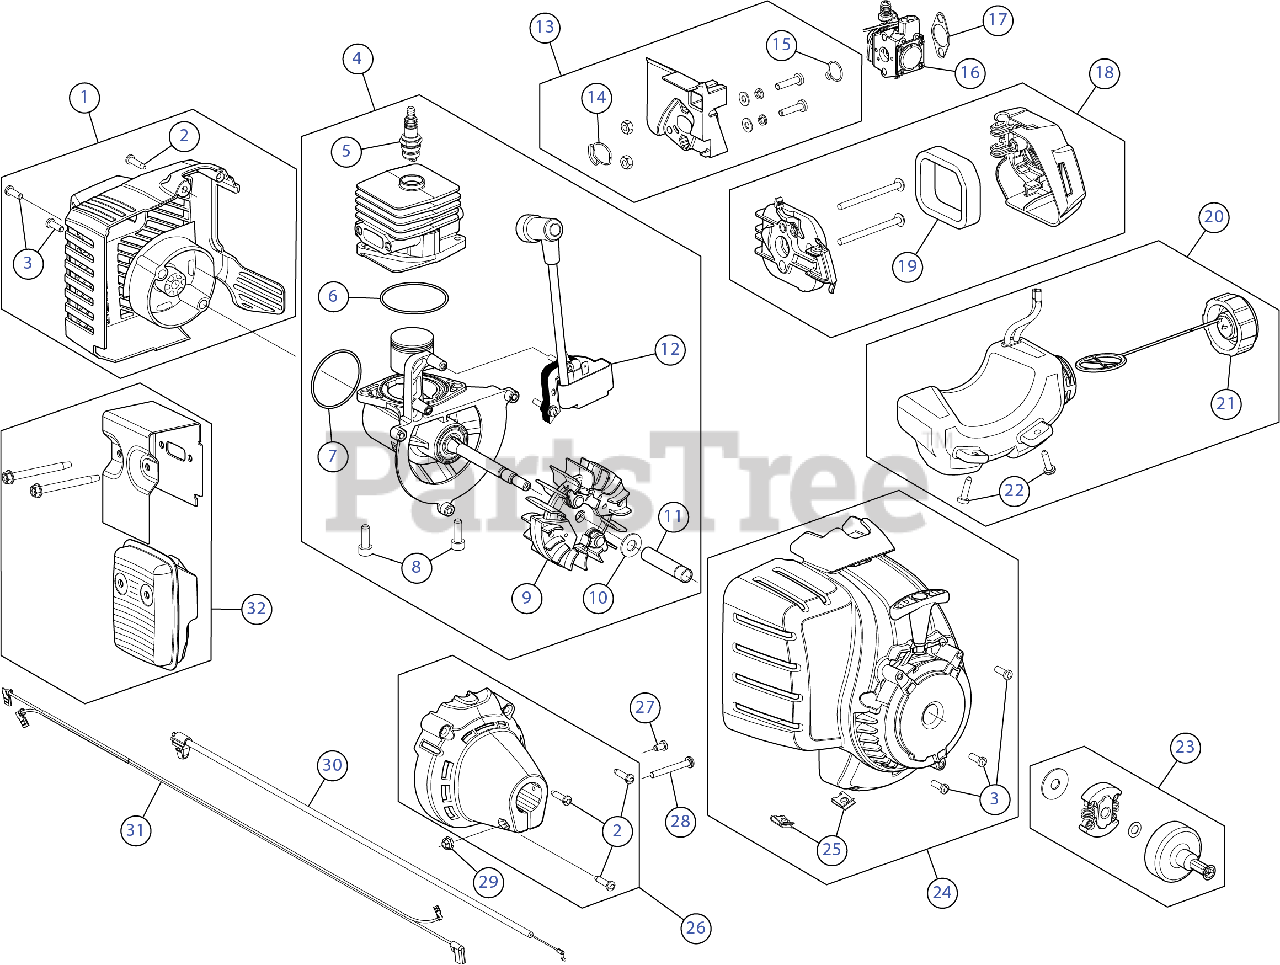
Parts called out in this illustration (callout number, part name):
1	ENGINE COVER RR
2	SCREW, #8-16X.750 PH
3	SCREW:10-32X.562:#8P
4	SHORT BLOCK
5	SPARK PLUG
6	O-RING
7	O-RING
8	SCREW, 1/4-20 x .75
9	FLYWHEEL ASSEMBLY
10	BELL WASHER
11	SPACER
12	MODULE DIG 8500
13	INTAKE ASSEMBLY
14	O-RING
15	O-RING
16	CARBURETOR
17	GASKET CARB
18	AIRCLEANER COVER ASSEMBLY
19	AIR FLITER
20	FUEL TANK ASSEMBLY
21	FUEL CAP ASSEMBLY
22	SCREW:10-6 x .75
23	SMALL CLUTCH ASSEMBLY W/SMALL DRUM
24	STARTER HOUSING REM
25	NUT, TINNERMAN U-T
26	CLUTCH COVER
27	SCREW, 8-32 x .312 P
28	SCREW
29	HEX NUT
30	THROTTLE CABLE
31	LEAD WIRES
32	MUFFLER ASSEMBLY
